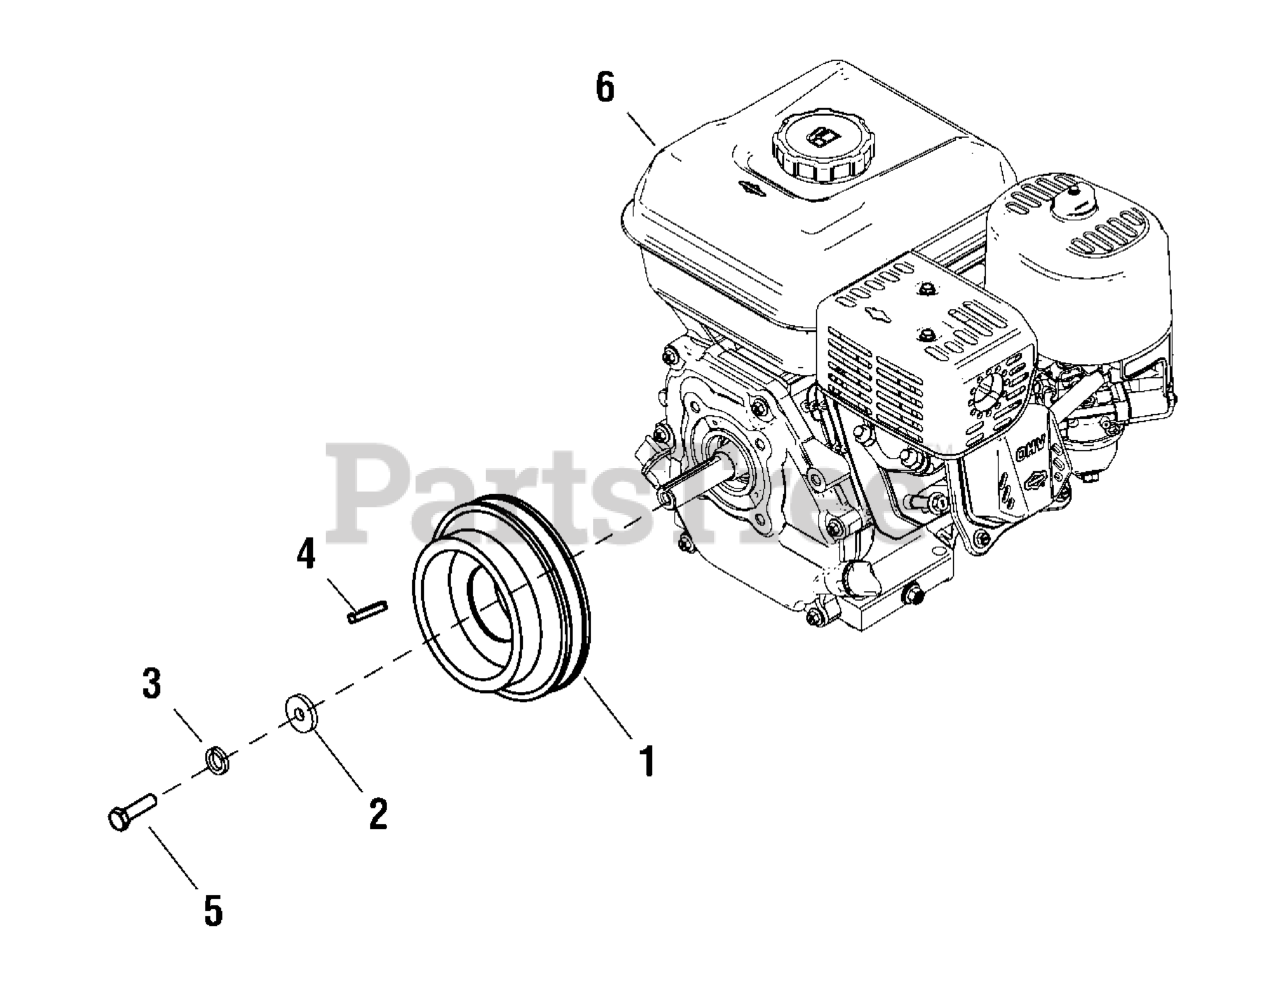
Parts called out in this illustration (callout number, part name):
1	CLUTCH
2	WASHER
3	WASHER, Spring
5	BOLT, Hex, M8 x 30
6	ENGINE, B&S
